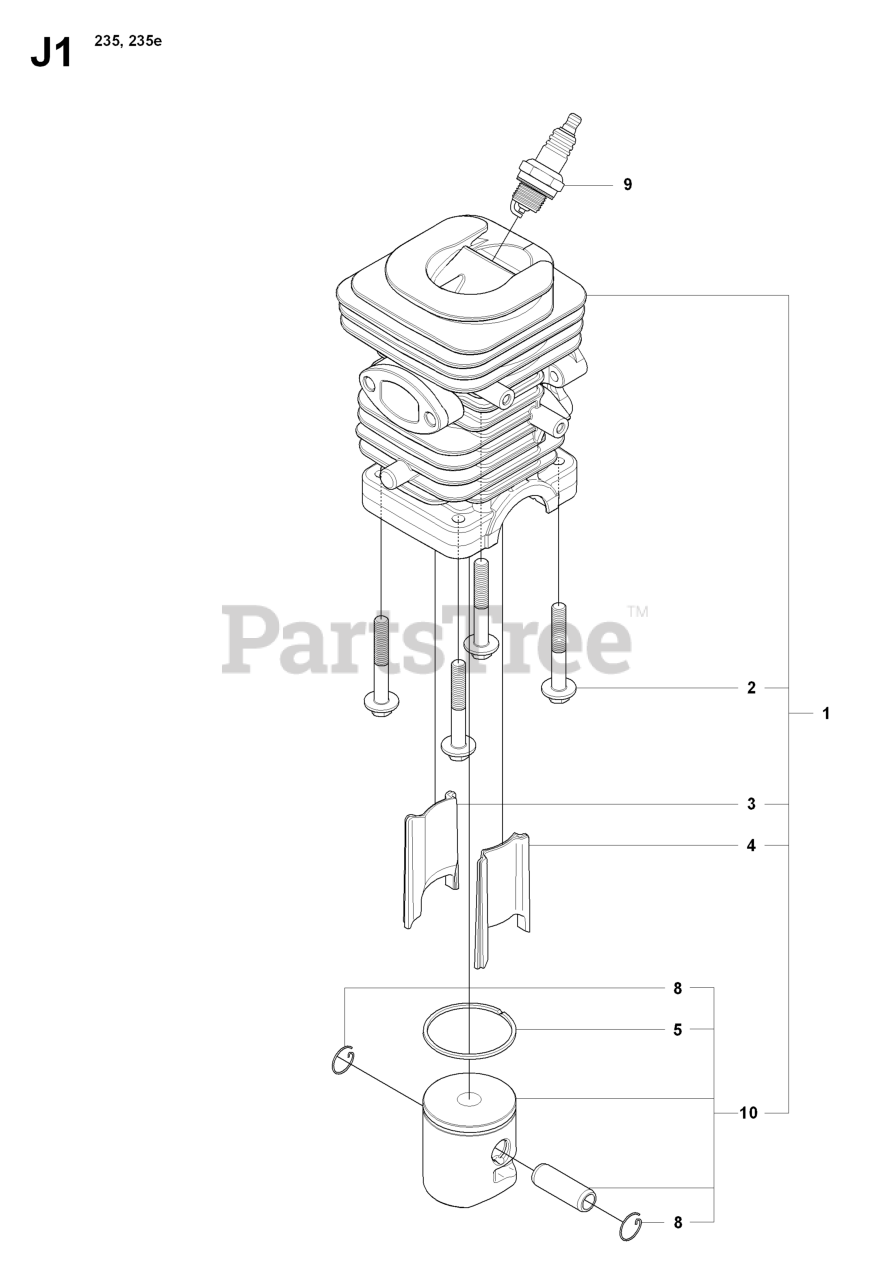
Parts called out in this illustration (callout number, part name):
1	KIT, CYLINDER & PISTON
3	TRANSFER INSERT LEFT
4	TRANSFER INSERT RIGHT
5	PISTON RING
8	C-CLIP,PSTN PIN 36/41
9	SPARK PLUG RCJ7Y
10	PISTON KIT
